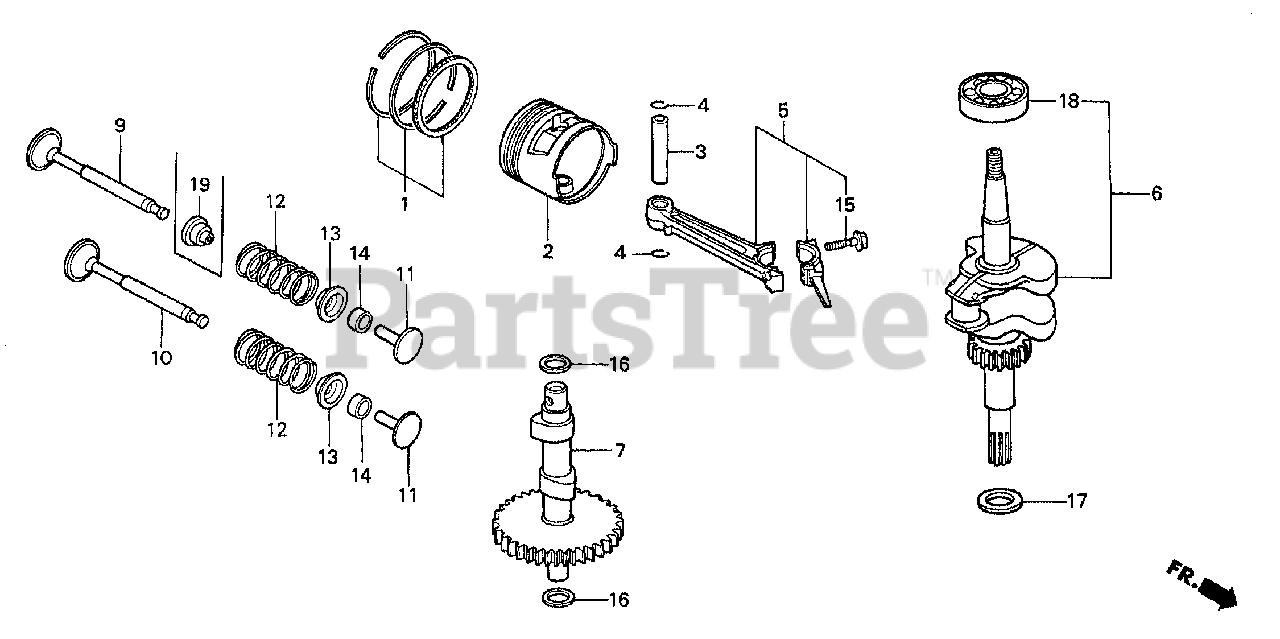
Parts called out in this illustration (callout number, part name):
1	RING SET, PISTON (STD)
1	RING SET, PISTON (OS 0.25)
1	RING SET, PISTON (OS 0.50)
1	RING SET, PISTON (0.75) (NOT AVAILABLE)
2	PISTON
2	PISTON (STD)
2	PISTON (OS 0.25)
2	PISTON (OS 0.50)
2	PISTON (0.75)
3	PIN, PISTON
4	CLIP, PISTON PIN (10MM)
5	ROD ASSY., CONNECTING (STD)
5	ROD ASSY., CONNECTING (UNDER SIZE) Use up to Engine SN 1214439.
6	CRANKSHAFT
9	VALVE, IN.
10	VALVE, EX.
11	LIFTER, VALVE
12	SPRING, VALVE
13	RETAINER, VALVE SPRING
14	ADJUSTER, TAPPET CLEARANCE (3.15)
14	ADJUSTER, TAPPET CLEARANCE (3.25)
14	ADJUSTER, TAPPET CLEARANCE (3.34)
14	ADJUSTER, TAPPET CLEARANCE (3.43)
14	ADJUSTER, TAPPET CLEARANCE (3.52)
14	ADJUSTER, TAPPET CLEARANCE (3.61)
14	ADJUSTER, TAPPET CLEARANCE (3.72)
14	ADJUSTER, TAPPET CLEARANCE (3.82)
15	BOLT, CONNECTING ROD
16	WASHER (12MM)
17	WASHER, THRUST (20X1.00)
18	BEARING, RADIAL BALL (6203)
19	SEAL, VALVE STEM
